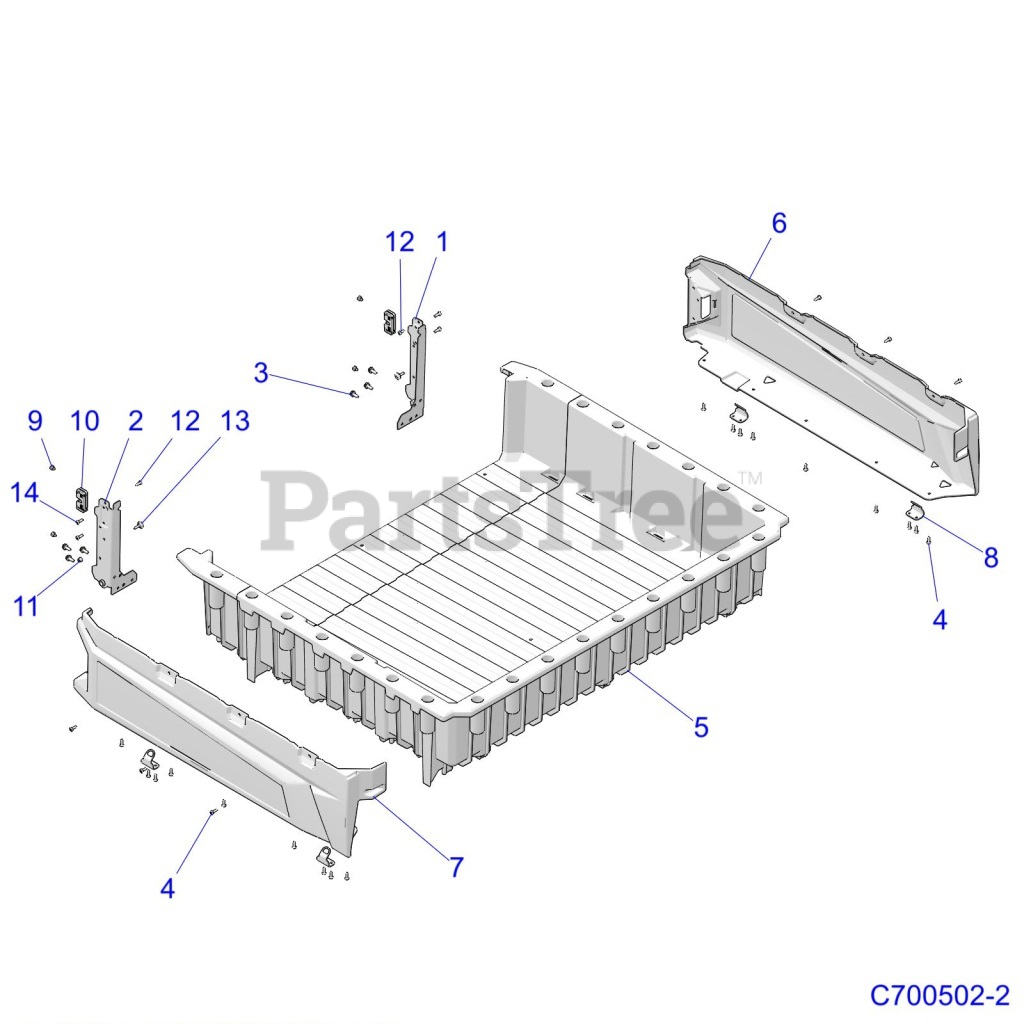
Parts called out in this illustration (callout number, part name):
1	WELD-TAILGATE SUPPORT,LH,BLK
2	WELD-TAILGATE SUPPORT,RH,BLK
3	BOLT-M8X1.25X20,HXFLG,TAP/R-OD
4	SCR-TXPH-#14 X .75 HI-LO RIE
5	K-BOX,LONG,ARNS,BLK
6	PANEL-BOX,LONG,LH,BLK
7	PANEL-BOX,LONG,RH,BLK
8	BRACKET, BOX TIE DOWN
9	BUMPER-RUBBER,13.50 DIAX4.3THK
10	LATCH, SLAM TAILGATE
11	NUT-M6 FLANGE,NYLOK
12	SCR-TX TRUSS-#14X3/4,HI/LO ZBK
13	SCR-TXTH-M6X1.0X25 RIE,SHDR
14	SCR-#14X3/4 HI/LO-PH-PN TRX-M
